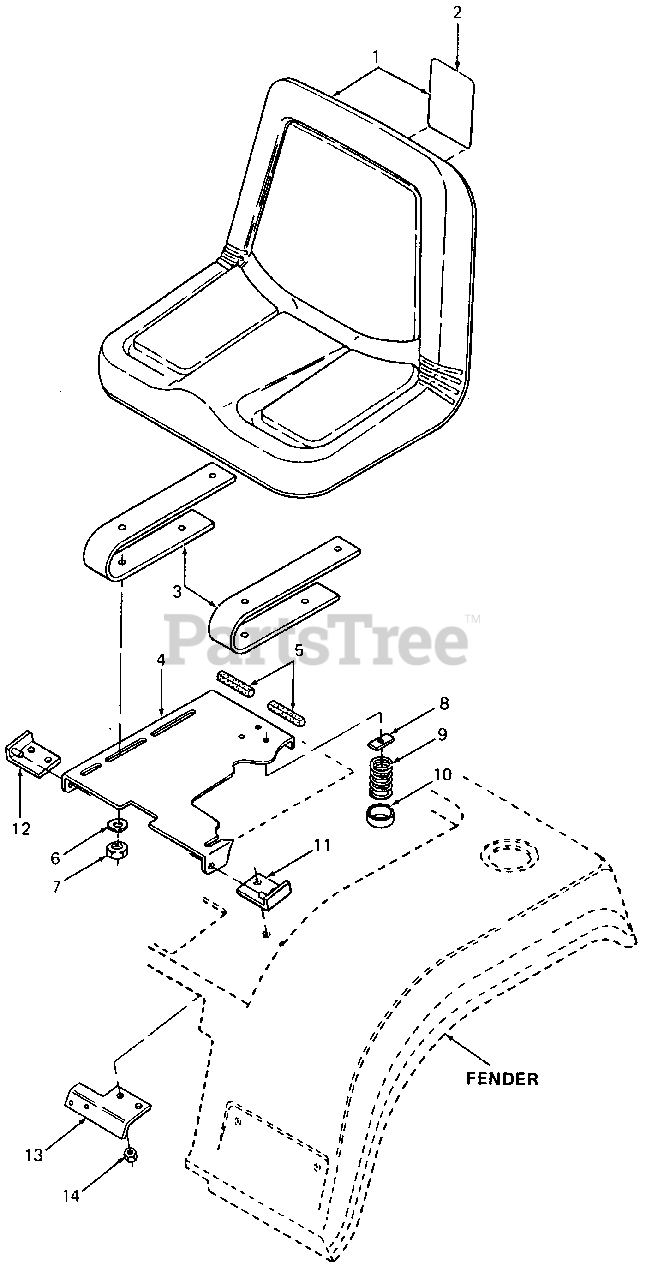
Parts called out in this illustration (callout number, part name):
1	Seat w/Graphic
2	Graphic, Caution
3	Spring, Seat
6	Washer, Bell, .345 X .88 X .06 Thk
7	Nut, Hex, 5/16-18 GR5
8	Nut, Spring, #10 X 1.88 Lg
9	Spring, Compression
10	Cap, Spring
13	Bracket, Reverse Switch
14	Nut, Hex Center Lock, 3/8-16
